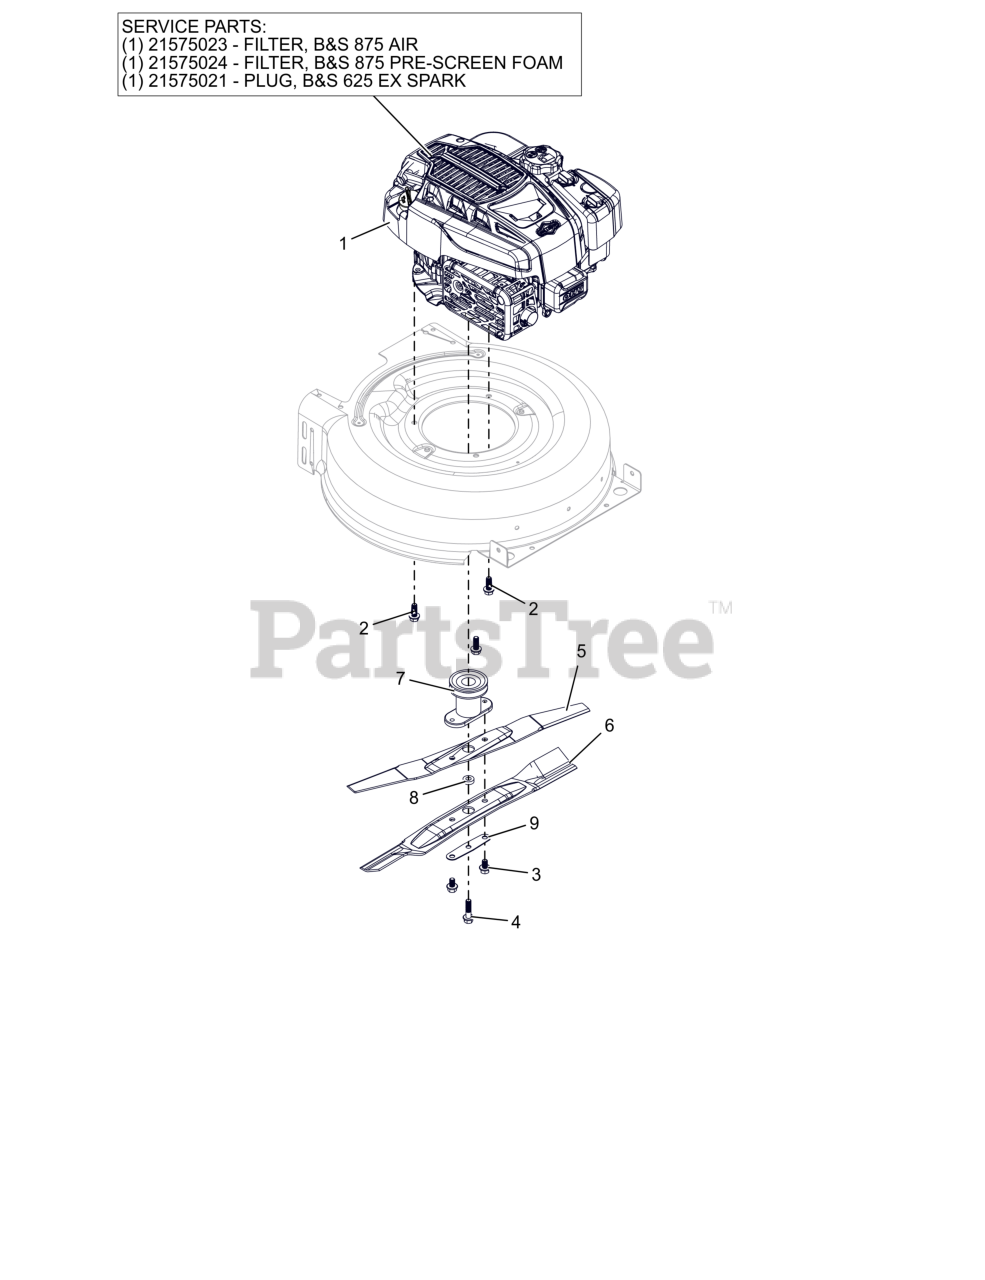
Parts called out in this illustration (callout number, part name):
1	ENGINE, BRIGGS 875 EXI MNS
1	FILTER- B&S 875 AIR
1	FILTER-B&S 875 PRE-SCREEN FOAM
1	PLUG- B&S 625 EX SPARK
2	SCR-TAP, 3/8-16X1.00 HWH
3	SCR, 3/8-16 x 5/8, HEX-FLG
4	SCR, HEX FLANGE 3/8-24X1.50
5	BLADE- DUAL UPPER - 21"
6	BLADE, DUAL LOWER - 21
7	SPCR, BLADE - DUAL
8	SPCR, BOLT (BLACK)
9	PLATE, SUPPORT DUAL BLADE (BLACK)
